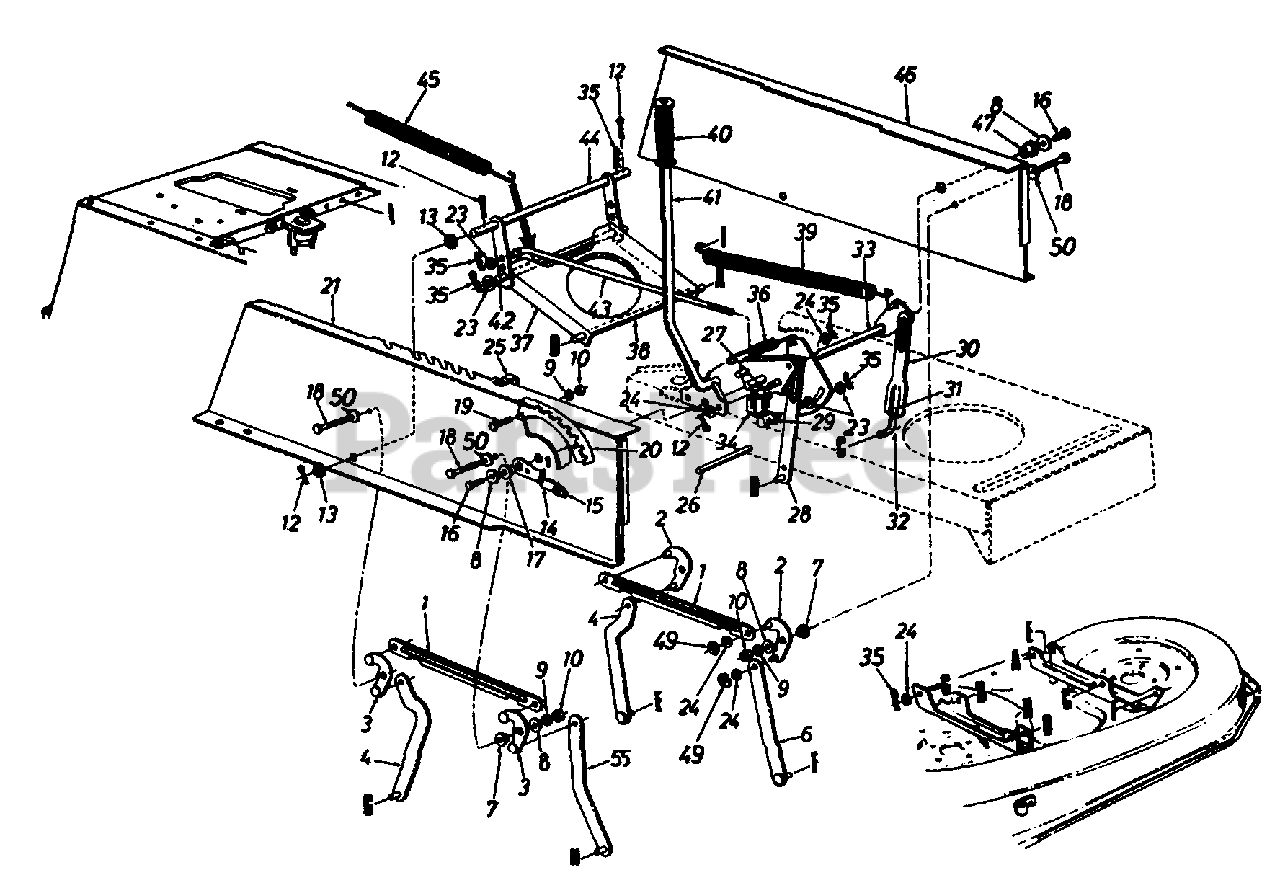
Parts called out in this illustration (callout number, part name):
3	Pivot Link Ass'y.- R.H.
7	Shld. Spacer .318" I.D.
8	F1-Wash. .344" I.D. x .62" O.D.
9	L-Wash. 5/16" I.D.
10	Hex Nut 5/16-18 Thd.- Gr. 5
12	Cotter Pin 1/8" Dia.
13	Fl-Wash. .635" I.D. x 1.0" O.D.
15	Knob
16	Hex Wash. TT-Tap Scr. 5/16-18 x .75" Lg.
17	Flange Brg. .63" I.D.
18	Hex Wash. Hd. Scr. 5/16-18 x .875" Lg.
19	Hex Bolt 5/16-18 x .75" Lg.
20	Index Brkt.
21	Upper Frame - R.H.
23	Fl-Wash. .385" I.D. x .87" O.D.
24	Fl-Wash. .531" I.D. x .93" O.D.
26	Running Board Rod
27	Hex Wash. Hd. Tap Scr.
31	Hex Nut 1/2-20 Thd. (Gr. 5)
32	Lift Link Adjuster
35	Inter. Cotter Pin 3/8" Dia.
36	Extension Spring
39	Extension Spring
40	Grip
41	Deck Lift Handle Ass'y.
42	Shaft 3/8" Dia. x 9.34" Lg.
43	Disengagement Rod
44	Stabilizer Shaft Ass'y.
45	Extension Spring 7.58" Lg.
49	"E"-Ring
50	Bell-Wash. .325" I.D.
